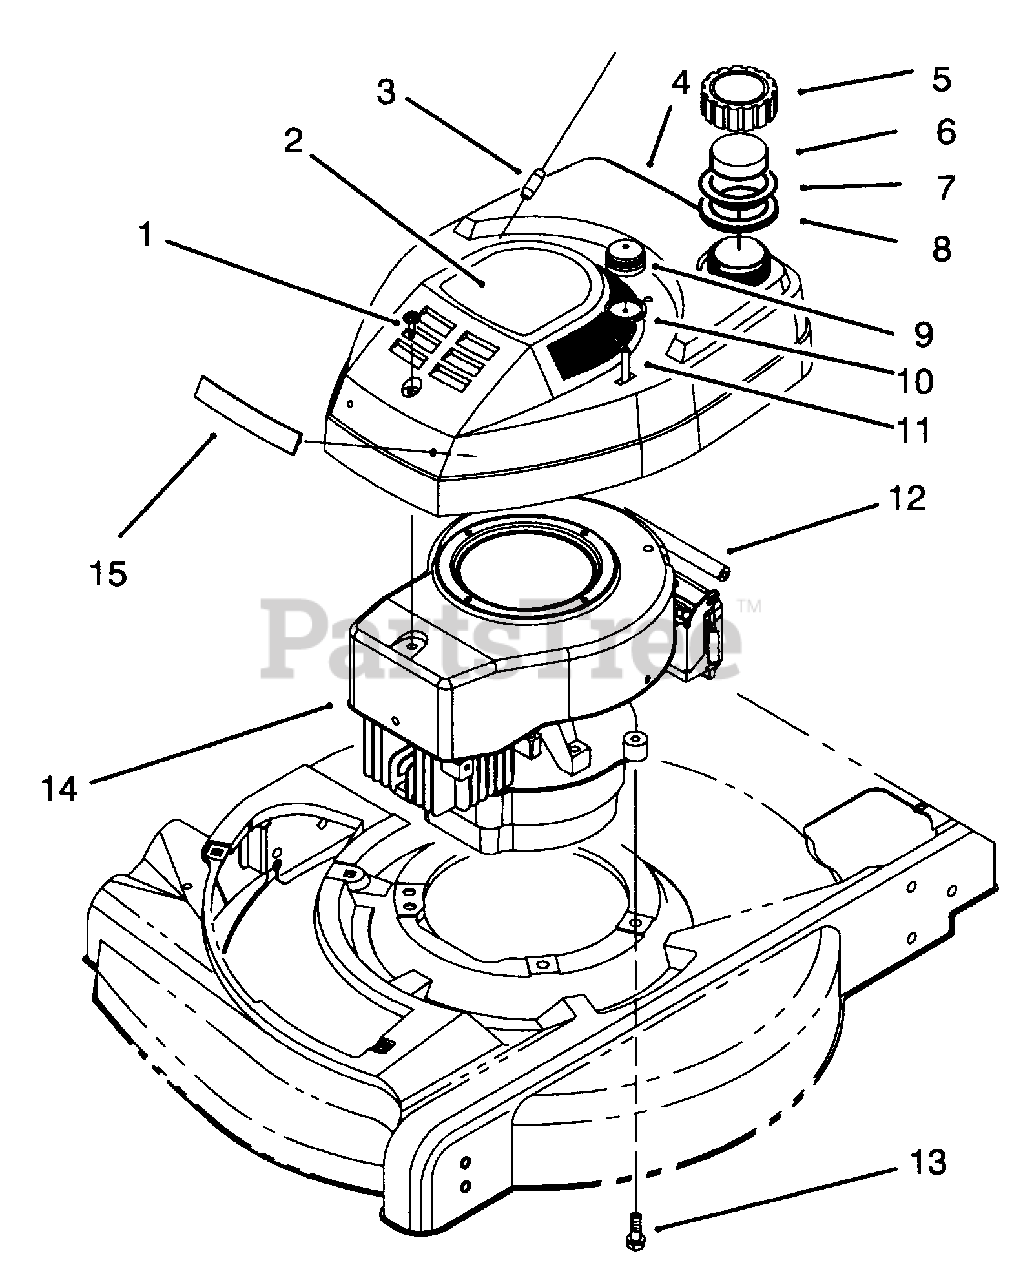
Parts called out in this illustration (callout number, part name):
1	Screw-Sems
2	Decal-Shroud (Model No. 10211 Only)
2	Decal-Shroud (Model No. 10312 Only)
3	Stop-Rope
4	Tank & Shroud
5	Gas Cap Assembly (Incl. Ref. #6-8)
9	Bulb-Primer
10	Body-Primer
11	Hose-Primer
12	Line-Gas
13	Screw-Engine
14	Engine
15	Applique-Shroud
